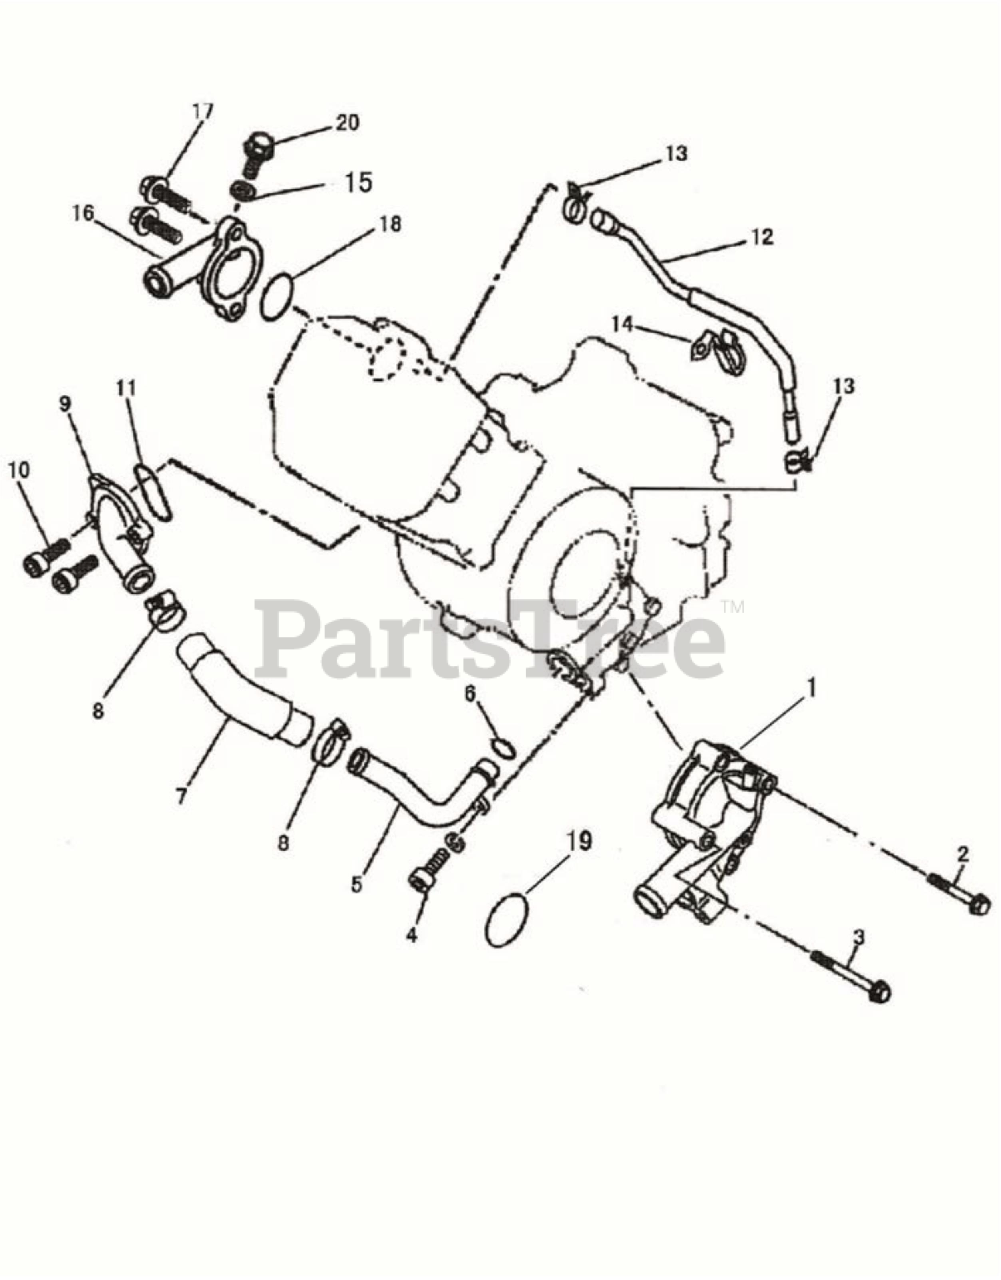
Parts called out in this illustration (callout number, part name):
1	Water Pump Assy
2	Hexagon flange bolts M6X45
3	Hexagon flange bolts M6X65
4	Hexagon flange bolts M6X16
5	Water pipe
6	O-Ring 20.7X2.6
7	Hose,Cylinder?Water In
8	Hose Clamp Assy 20?32
9	Hose Joint,Cylinder,Water Out
10	Hexagon flange bolts M6X20
11	O-Ring 33.4X2.4
12	Water pipe
14	Pipe Clamp
15	Aluminum Washer 6X12X1.5
16	Cover,Thermostat
17	Hexagon flange bolts M6X20
18	Seal,thermostat cover
19	O-Ring 34.2X2.5
20	Hexagon flange bolts M6X12
